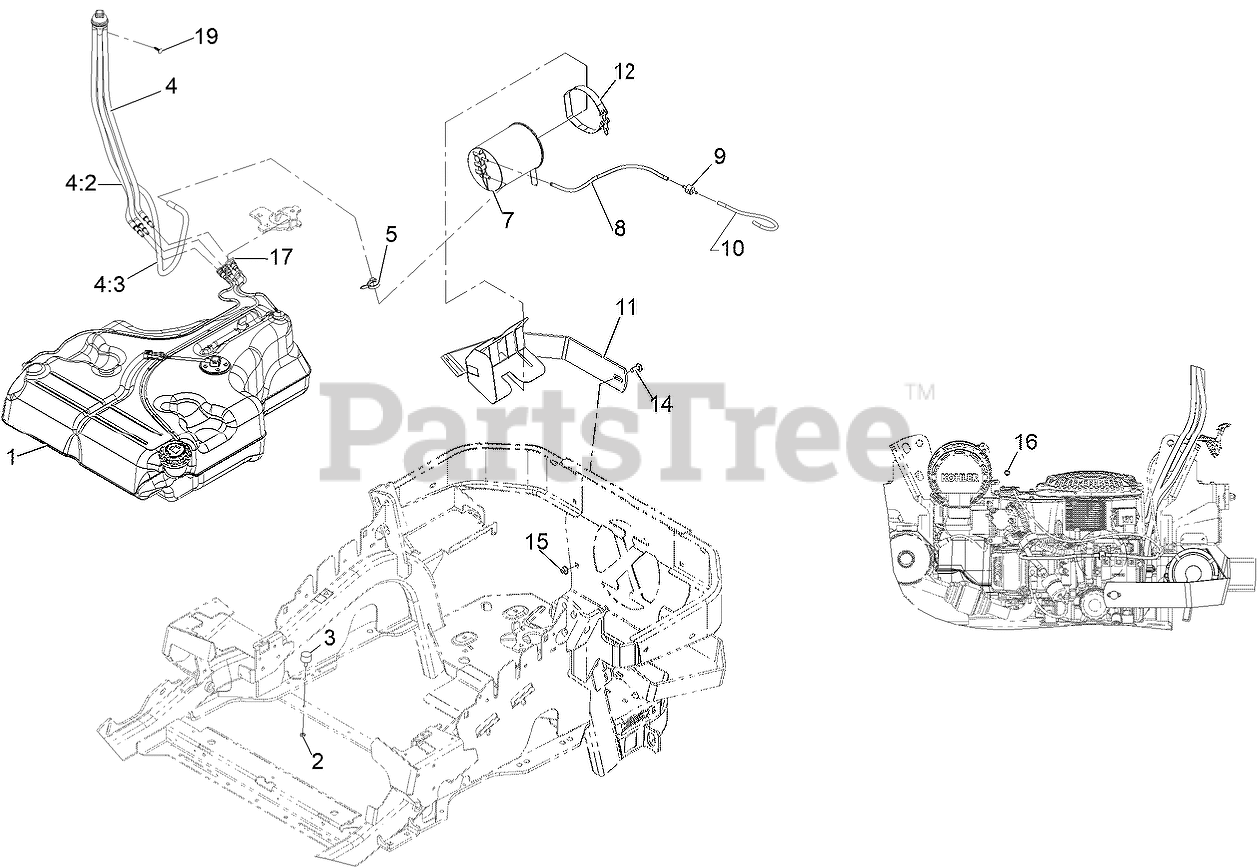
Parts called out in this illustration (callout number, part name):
1	FUEL TANK ASM
2	NUT-JAM
4	FUEL MANIFOLD VENT ASM
4:2	HOSE-FUEL
4:3	HOSE-FUEL
5	CLAMP-HOSE
7	CANISTER-CARBON, 1200CC
8	HOSE-VENT, FORMED
9	VALVE-CHECK, VACUUM
10	HOSE-VENT, FORMED
11	MOUNT-CANISTER
12	CLAMP, T-BOLT
14	SCREW-CARR
15	NUT-HF, NI
16	PLUG-PORT
17	RETAINER-LINE, VAPOR
19	PLUG-PLASTIC
